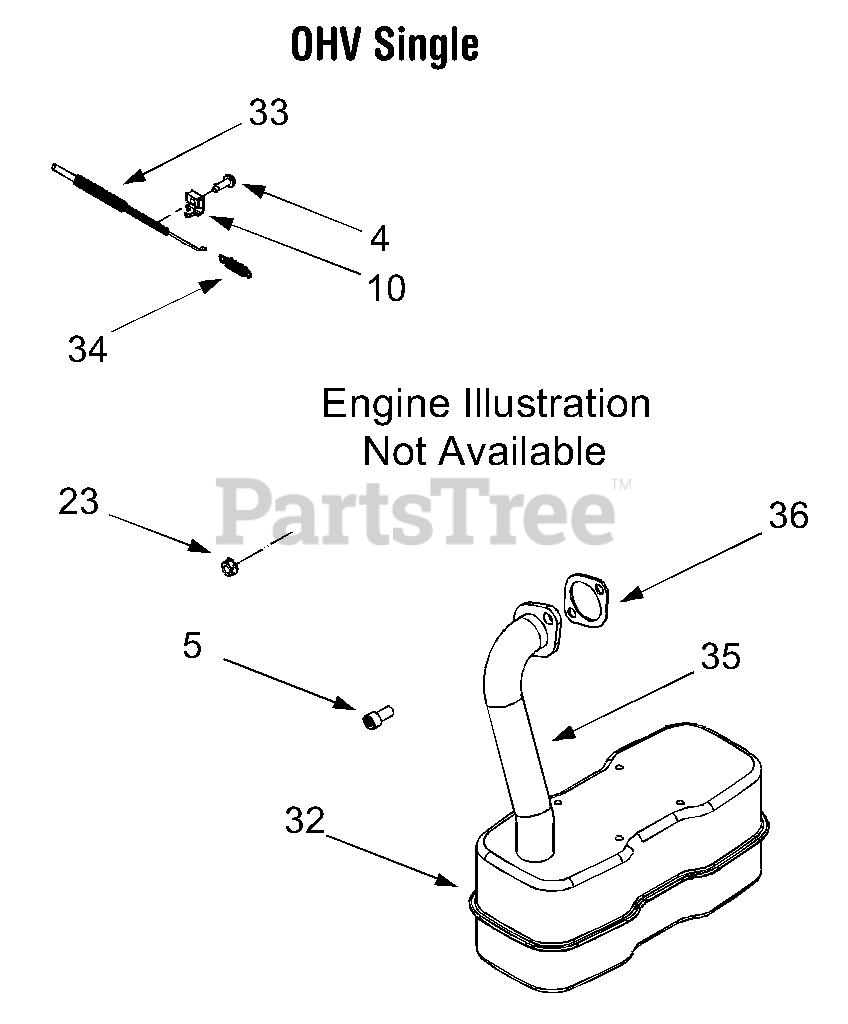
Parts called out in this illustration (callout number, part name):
4	Screw, #10-32 x .625 (OHV V-Twin)
5	Socket Cap Screw, 5/16-18 x .625
10	Casing Clamp (OHV Single)
23	Hex Sems Nut, 1/4-20 (OHV V-Twin)
32	Muffler, Single Inlet (OHV Single)
33	Throttle Cable (OHV Single)
34	Extension Spring, .275 x 1.25 (OHV Single)
35	Exhaust Pipe (OHV Single)
36	Exhaust Gasket (OHV Single)
